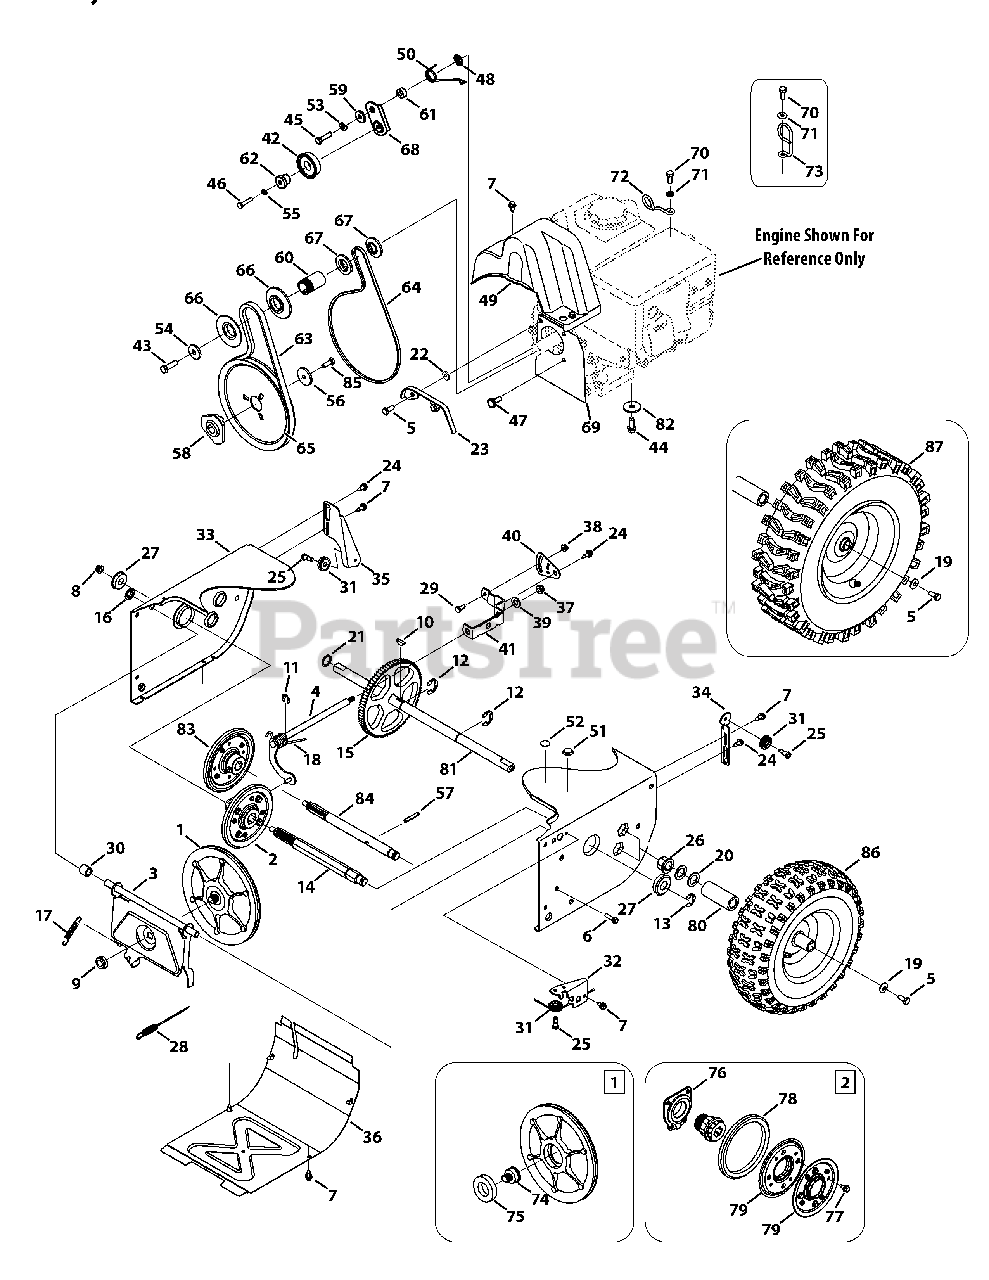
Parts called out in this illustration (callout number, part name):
1	Disc Assembly, Friction Wheel
2	Friction Wheel Assembly, 5.5 OD
4	Rod Shift Assembly
5	Hex Head Screw, 5/16-24 x .750
6	Taptite Screw, 1/4-20 x 1.000
7	Taptite Screw, 1/4-20 x .625
8	Flange Lock Nut, 3/8-16
9	Flange Nut, 5/8-18
10	Hi-pro Key, 3/16 x 3/4 Dia.
12	Retaining E-Ring, .875 Dia.
13	E-Ring, .750 Dia.
14	Hex Shaft, 7-Tooth
15	Gear, 80-Tooth
16	Speed Nut, .500
17	Extension Spring
18	Torsion Spring, .750 x .968
19	Bell Washer, .340 x .872 x .060
20	Flat Washer, .793 x 1.24 x .060
21	Flat Washer, .75 x 1.00 x .060
22	Washer, Flat, .385 x .62 x .063
23	Belt Cover
24	Shoulder Screw, .368 x .113, 1/4-20
25	Shoulder Screw, 1/4-28, .340 x .355
26	Hex Flange Bearing
27	Ball Bearing, 17 x 40 x 12
28	Wheel Clutch Cable, 44.95"
29	Hex Head Screw, 1/4-20 x .620
30	Spacer, .508 ID x .75 OD x .68
31	Cable Roller
32	Auger Cable Front Guide Bracket
33	Frame
34	Auger Cable Guide Bracket
35	Drive Cable Guide Bracket
37	Flange Lock Nut, 5/16-18
38	Flange Lock Nut, 1/4-20
39	Washer, Flat, .469 x .875 x .105
40	Speed Selector Pivot Bracket
41	Speed Selector Shift Bracket
42	Idler Pulley Assembly
43	Hex Screw, 3/8-24 x 1.25
44	Sems Screw, 3/8-16 x 1.00
45	Hex Screw, 5/16-24 x 1.25
46	Hex Screw, 1/4-20 x 1.25
47	Shoulder Screw, 5/16-24 x .5
48	Push-on Nut, .25 Dia.
49	Belt Cover, 4-Way Large block engine
49	Belt Cover, 4-Way
49	Belt Cover, Standard
50	Torsion Spring, .850 ID x .333
51	Plug, 3/8 ID
52	Plug, 1/2 ID
53	Lock Washer, 5/16
54	Flat Washer, .406 x 1.25 x .157
55	Washer, Lock, 1/4
56	Flat Washer, .34 x 1.50 x .150
57	Pin, Spirol, 2.5"
58	Adapter Pulley, .75 Dia.
59	Shoulder Spacer, .3175 x .5 x .0975
60	Spacer, .875 ID x 1.185 OD
61	Spacer, .340 x .750 x .330
62	Shoulder Space, .260 x .785 x .538
63	Auger Drive Belt, 4-Way Large Block engine
63	Auger Drive Belt, Standard
64	Wheel Drive Belt, 4-Way Large Block engine
64	Wheel Drive Belt, Standard
65	Auger Drive Pulley, 8.1 x .5
66	Pulley Half, 2.600 OD
67	Pulley Half, 3/8 x 1.716 OD
68	Wheel Drive Idler Bracket
69	Cover Plate, 4-Way Large Block engine
69	Cover Plate, Standard
70	Hex Head Screw, 1.25 x 20
71	Washer, Flat, .330 x .630 x .0635
72	Cable Guide
73	Cable Guide
74	Friction Disc Bearing Pin
75	Ball Bearing, 30 x 55 x 13
76	Bearing Assembly
77	Screw, 1/4-14 x .625
78	Friction Wheel Rubber
79	Friction Wheel Plate
80	Spacer, 1.25 x .75 x 3.0
81	Axle, .75 x 22
82	Washer, Flat, .38 x 1.38 x .125
83	Friction Wheel Ass’y, Single-Speed
84	Shaft, Single-Speed
85	Hex Cap Screw, 5/16-24 x .875
87	X-Trac Wheel, 13 x 4 x 6, LH
87	X-Trac Wheel, 13 x 4 x 6, RH
87	X-Trac Wheel, 15 x 5 x 6, LH
87	X-Trac Wheel, 15 x 5 x 6, RH
87	X-Trac Wheel, 16 x 4.8 x 8, LH
87	X-Trac Wheel, 16 x 4.8 x 8, RH
